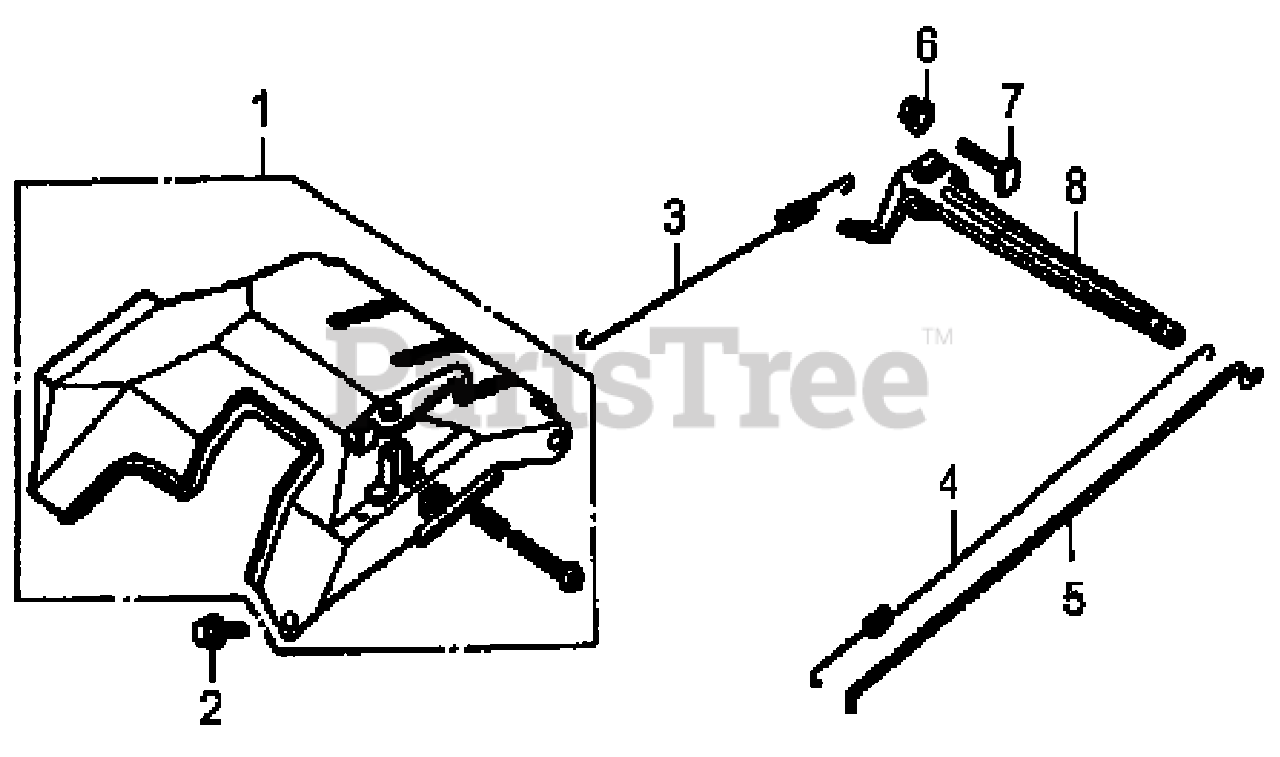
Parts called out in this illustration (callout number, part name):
1	CONTROL ASSY.
2	BOLT, FLANGE, 6×12
3	SPRING, GOVERNOR A
4	SPRING, GOVERNOR B
5	ROD, GOVERNOR
6	NUT, FLANGE, M6
7	BOLT, GOVERNOR ARM
8	ARM, GOVERNOR
